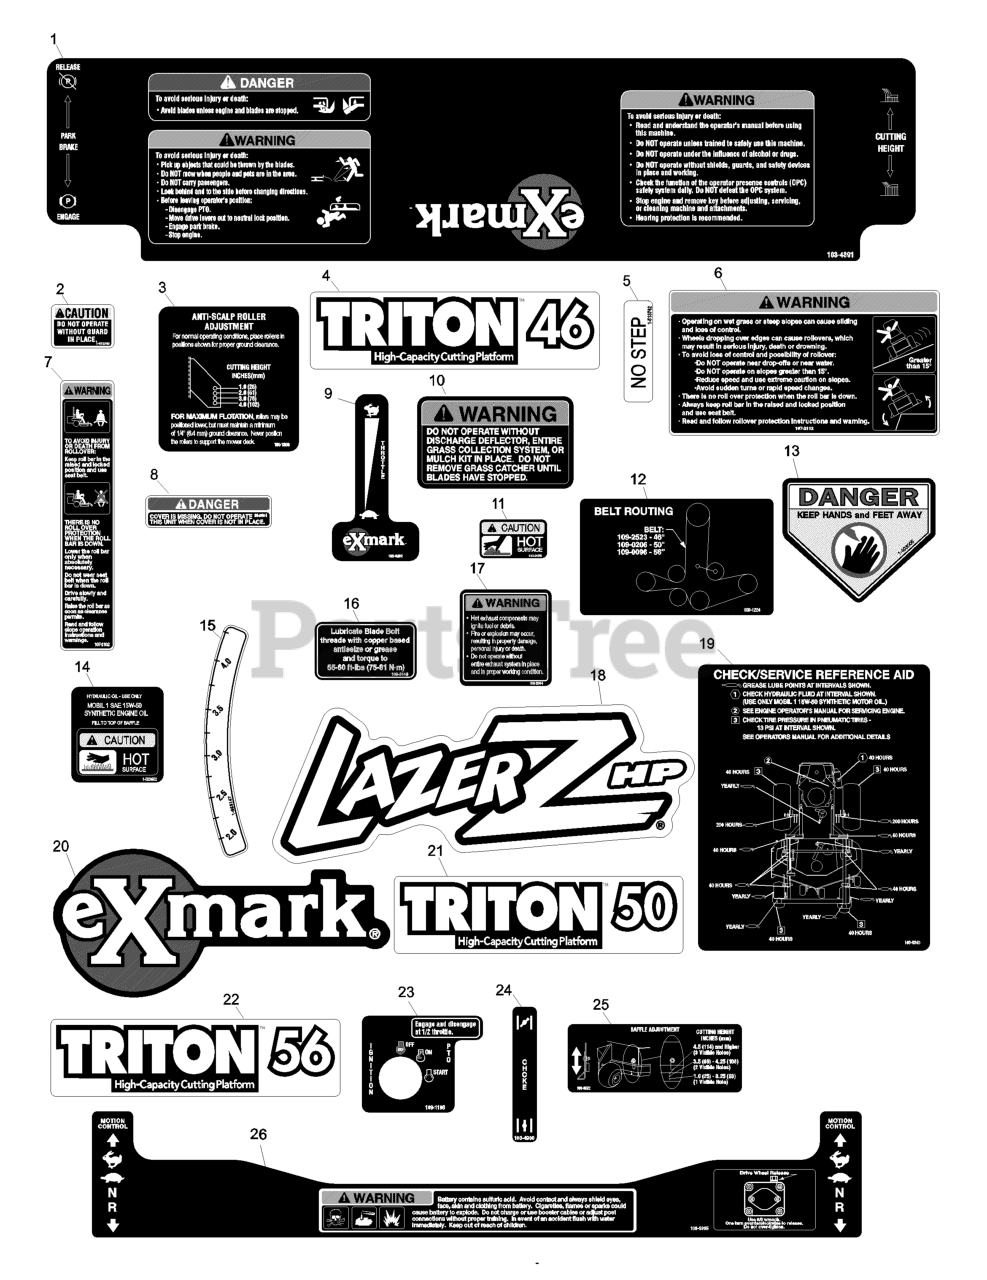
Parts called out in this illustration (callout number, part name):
1	DECAL,CONSOLE LHP
2	DECAL-GUARD
3	DECAL,ANTISCALP
4	DECAL,TRITON 46
5	DECAL,NO STEP
6	DECAL-WARNING
7	DECAL-WARNING, FOLDING RO
8	DECAL-COVER, MISSING
9	DECAL,THROTTLE
10	DECAL-WARNING, DISCHARGE
11	DECAL-CAUTION
12	DECAL,BELT ROUTING
13	DECAL-DANGER
15	DECAL-DECK HEIGHT, INNER
16	DECAL,BOLT TORQUE
17	DECAL-EXHAUST
18	DECAL,LHP MODEL
19	DECAL,CHECK/SERVICE LHP
20	DECAL,EXMARK LOGO
21	DECAL,TRITON 50
22	DECAL,TRITON 56
23	DECAL,IGNITION/PTO
24	DECAL,CHOKE
25	DECAL,BAFFLE ADJUSTMENT
26	DECAL-WARNING
